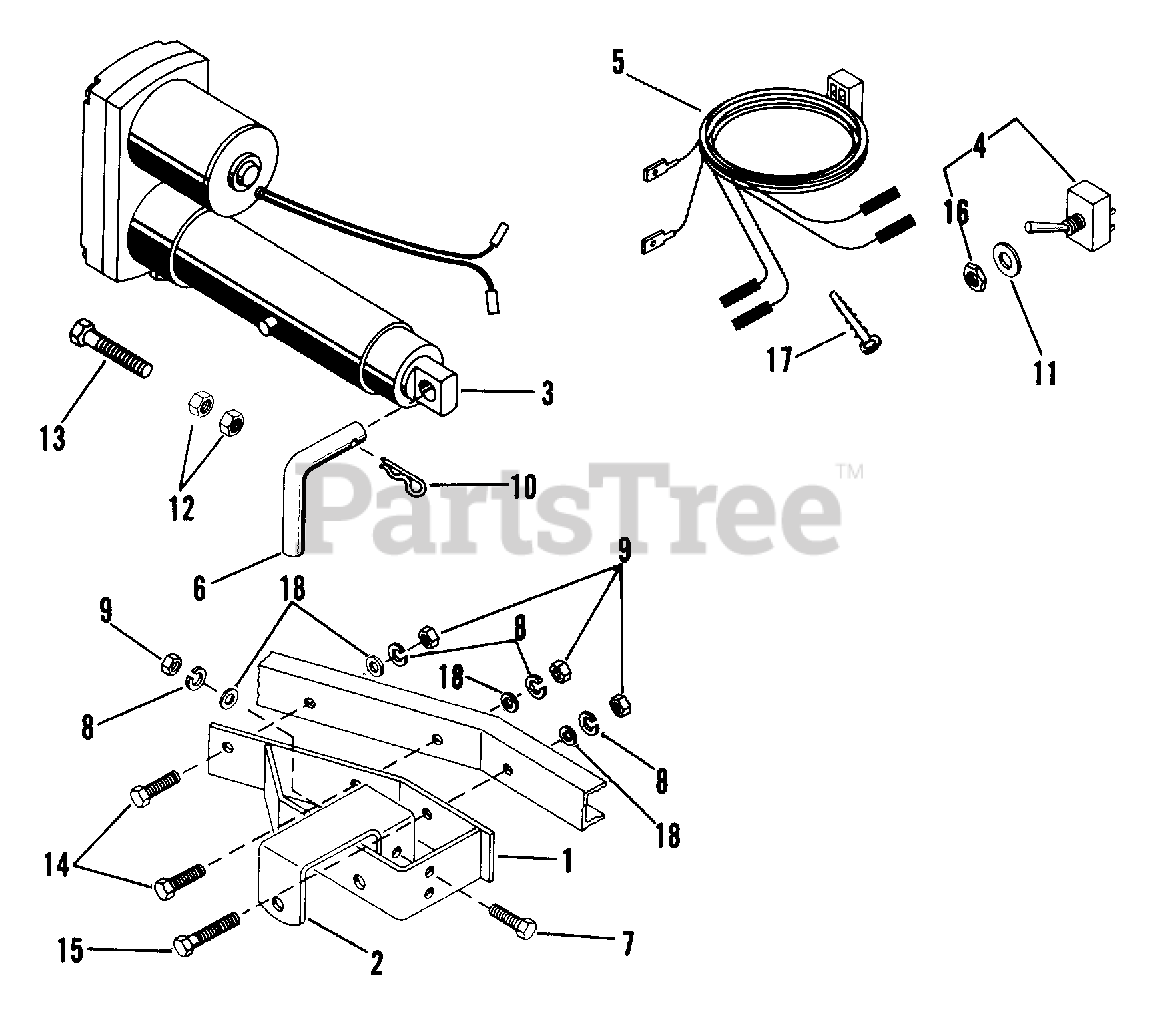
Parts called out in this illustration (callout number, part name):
1	CYLINDER MOUNT
2	CYLINDER RETAINER
3	ACTUATOR
4	SWITCH ASSEMBLY
5	WIRING HARNESS
7	BLT-HEX .38-16X1.00 PL GR5
8	WSHR-LK .375X.115 HVY PL
9	NUT-HEX .375-16
10	PIN-HAIR INT .09X.188 PL
11	WSHR-FL-STL .522X.735X.031 PL
12	NUT-JAM .625-11
13	BLT-HEX .62-11X1.75 PL GR2
14	BLT-HEX .38-16X1.25 PL GR5
15	BLT-HEX .38-16X2.00 PL GR5
16	NUT-THIN .50-28 PL INDAK
17	TIE DOWN
18	WSHR-FL-STL.406X.812X.065PL
19	WIRE HARNESS & SWITCH ASSEMBLY
